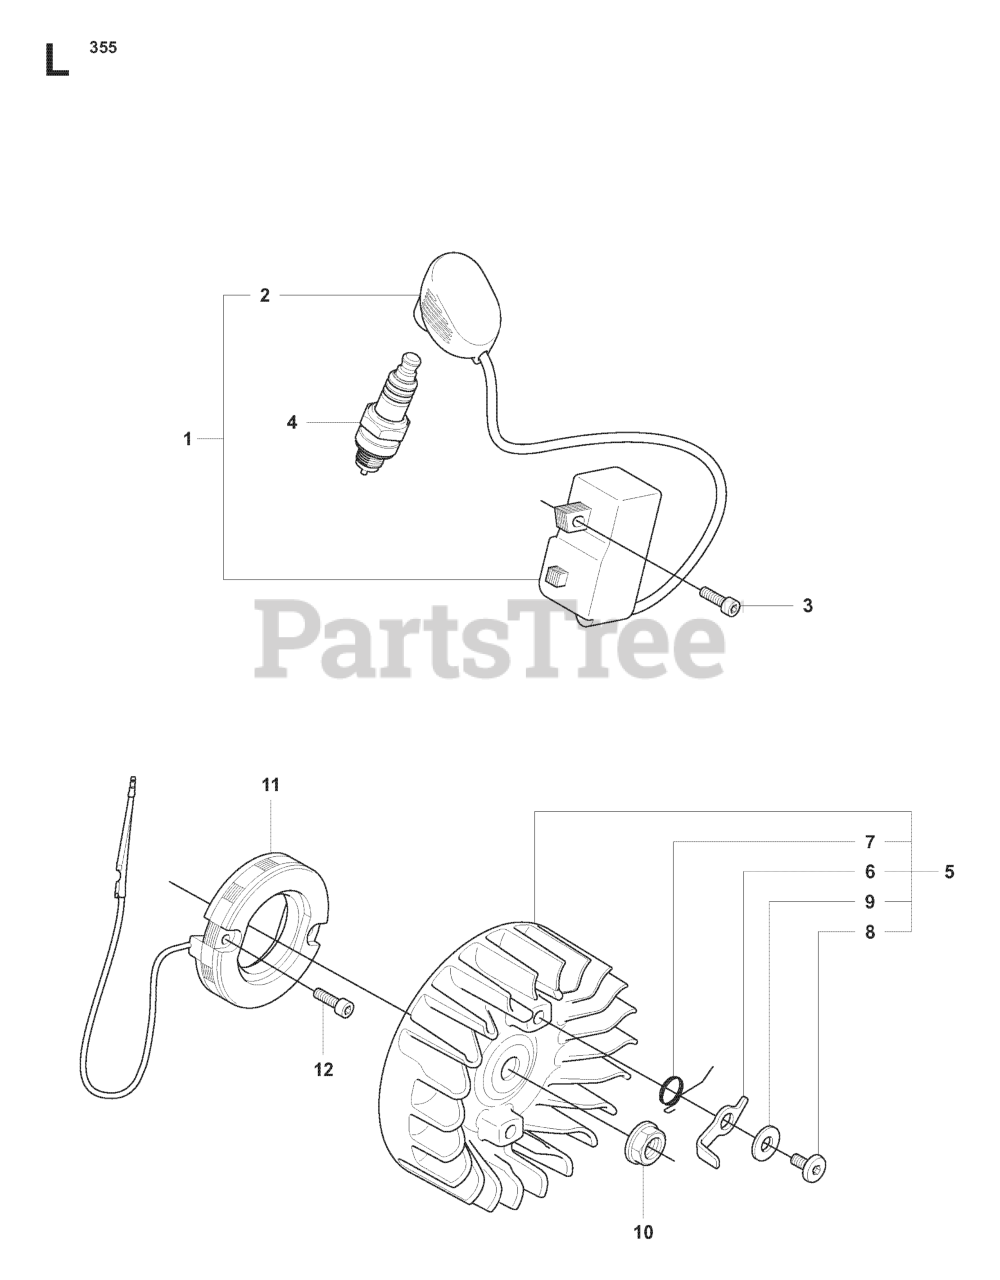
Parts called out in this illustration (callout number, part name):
1	IGNITION MODULE
1	RP IGNITION SYSTEM
2	SPARK PLUG CAP
4	SPARK PLUG M14X1.25 NGK BPMR7A
5	FLYWHEEL ASSY
6	STARTER PAWL
7	SPRING
10	NUT W/ WASHER
11	GENERATOR STARTER
12	SCREW
